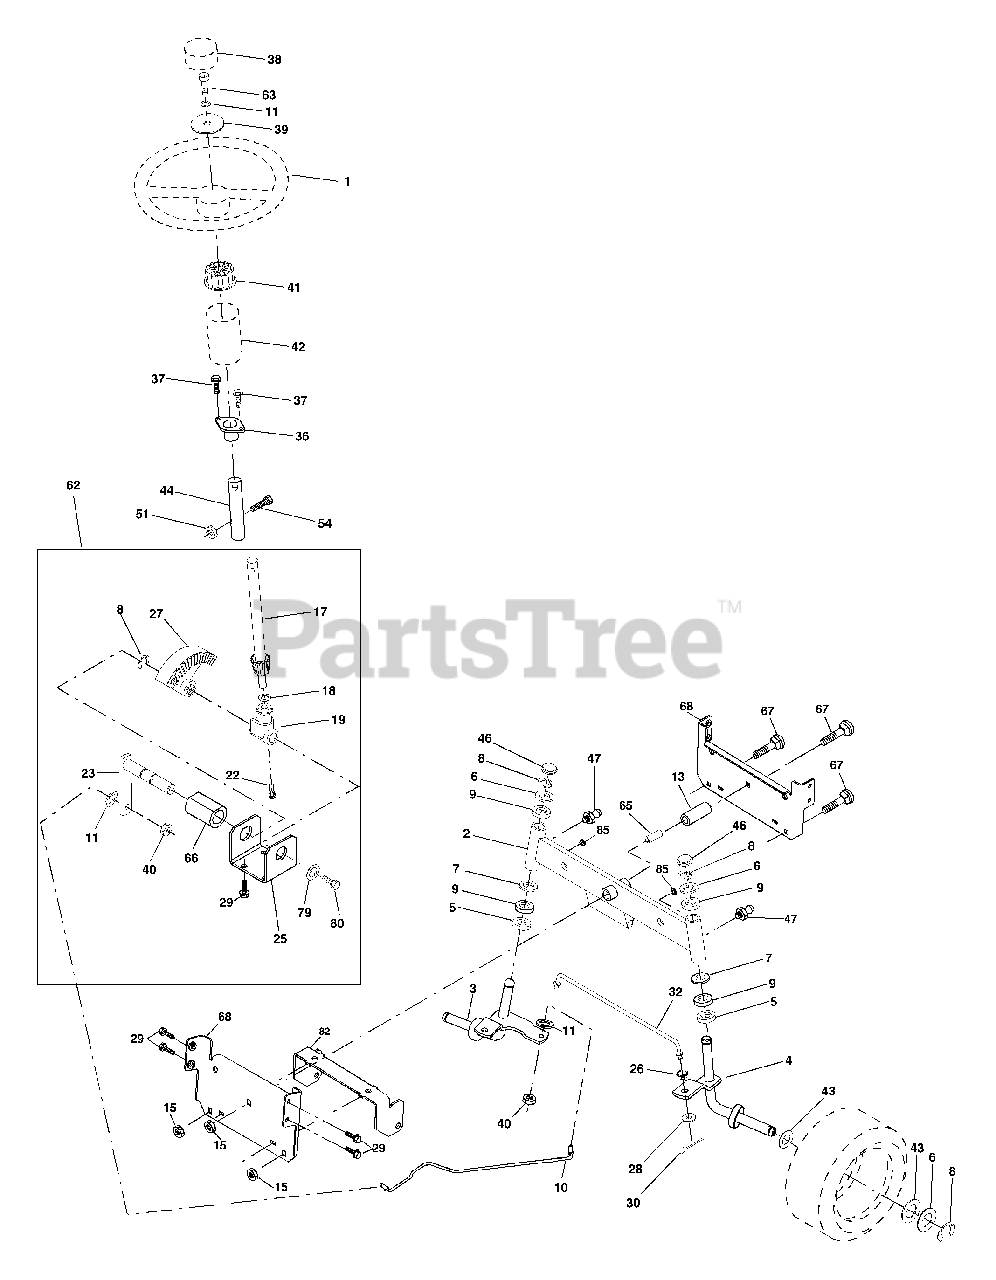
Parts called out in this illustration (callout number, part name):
1	Wheel Steering Auto Black
2	Axle Asm Front
3	Spindle Asm Lh
4	Spindle Asm Rh
5	Bearing Race Thrust Harden
6	Washer 25/32 X 1 5/8 X 16ga
7	Washer 27/32 X 1 1/4 X 16 Ga
8	Ring Klip #t5304-75
9	Bearing Col Strg Blk
10	Link Drag
11	Lockwasher
13	Spacer Bearing Axle Front
15	Nut Hex flange Lock
17	Shaft Asm Strg 5/8 X 15 19 Lt
18	Washer Thrust 515x 750x 033
19	Support Shaft
22	Screw Hex Wsh Hd Torx
23	Shaft Asm Pittman
25	Bracket Steering
26	Bushing Rod Tie Blk Lt
27	Gear Sector
28	Washer 13/32 X 7/8 X 16ga
29	Screw 3/8-16x3/4
30	Pin
32	Rod Tie Wire Form 19 75 Mech
36	Bushing Strg 5/8 Id Dash
37	Screw TT #10-32 x 5 x 3/8 Flange
38	Insert Cap Strg
39	Washer 13/32 X 2-3/8 X 12 Ga
40	Locknut Center
41	Adaptor Wheel Strg 640/ 635id
42	Boot Dash Steering
43	Washer 25/32 X 1 1/4 X 16 Ga
44	Extension Steering Non-Adjust
46	Cap Spindle Fr Top Blk
47	Fitting Grease
51	Nut Lock Hex W/Ins.
54	Bolt Fin Hex 5/16-18 Unc P
62	Kit Steering Assembly Service
63	Bolt Fin Hex 3/8-16unc x Gr. 5
65	Spacer Axle
66	Bearing Arm Pittman
67	Bolt Rdhd Sq 3/8-16 Unc x 2-1/4
68	Brace Axle
79	Washer 13/32 x 1-1/4 x 12 Ga.
80	Bolt Hex Nylon 3/8-16 x 3/4
82	Bracket Susp Chassis Front
85	Fastner Christmas Tree
